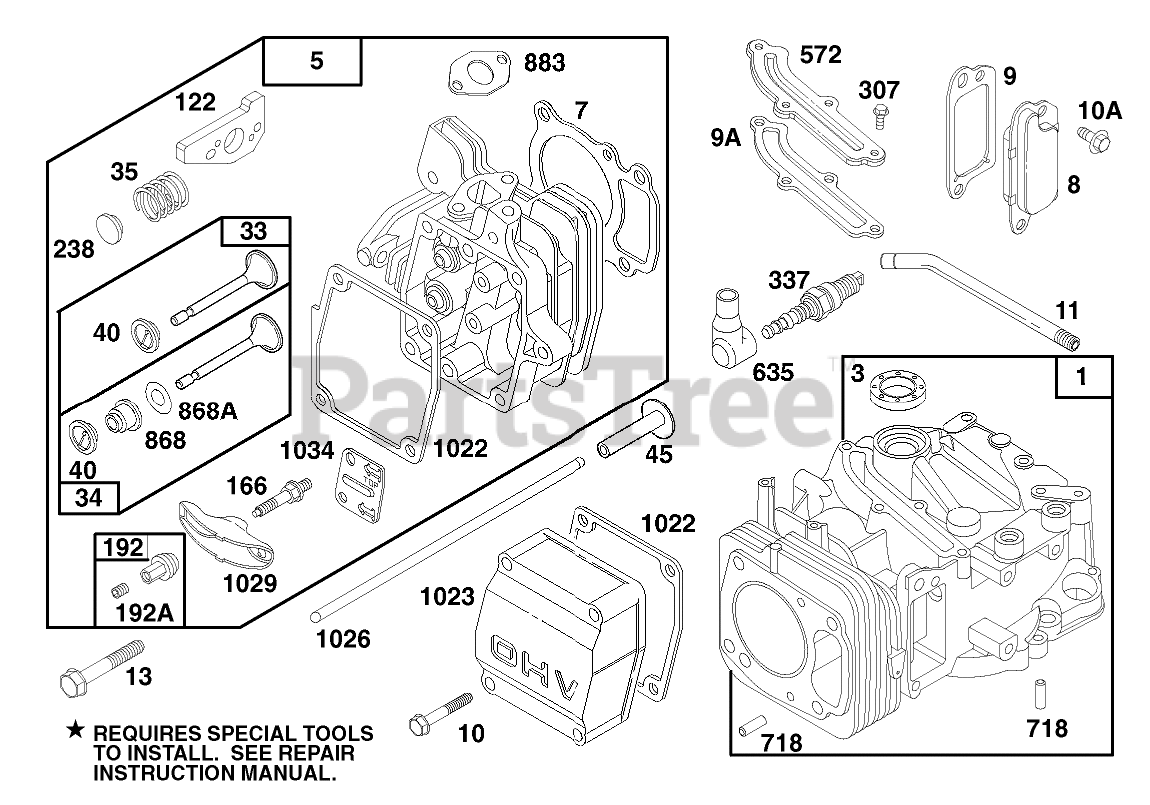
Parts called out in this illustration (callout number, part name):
1	CYLINDER ASSEMBLY
3	SEAL - OIL
5	CYLINDER HEAD
7	CYLINDER HEAD GASKET
8	Breather Assy
9	BREATHER GASKET
9A	GASKET-BREATHER
10	HEX HEAD SCREW
10A	HEX HEAD SCREW
11	TUBE - BREATHER
13	CYLINDER HEAD SCREW
33	EXHAUST VALVE
34	INTAKE VALVE
35	VALVE SPRING
37	GUARD - FLYWHEEL
40	SPRING RETAINER
45	VALVE TAPPET
122	ADAPTER ASSEMBLY
166	ROCKER ARM STUD
192	NUT - HEX SPECIAL
192A	SCREW SET
238	VALVE CAP
307	SCREW - SEM
337	PLUG-SPARK
572	BAFFLE - CYCLINDER
635	SPARK PLUG ELBOW
718	DOWEL - SLEEVE
868	SealAssy-Valve
868A	Seal-Valve
883	EXHAUST GASKET
1022	ROCKER COVER GASKET
1023	COVER - VALVE
1026	PUSH ROD
1029	ROCKER ARM
1034	PUSH ROD GUIDE
